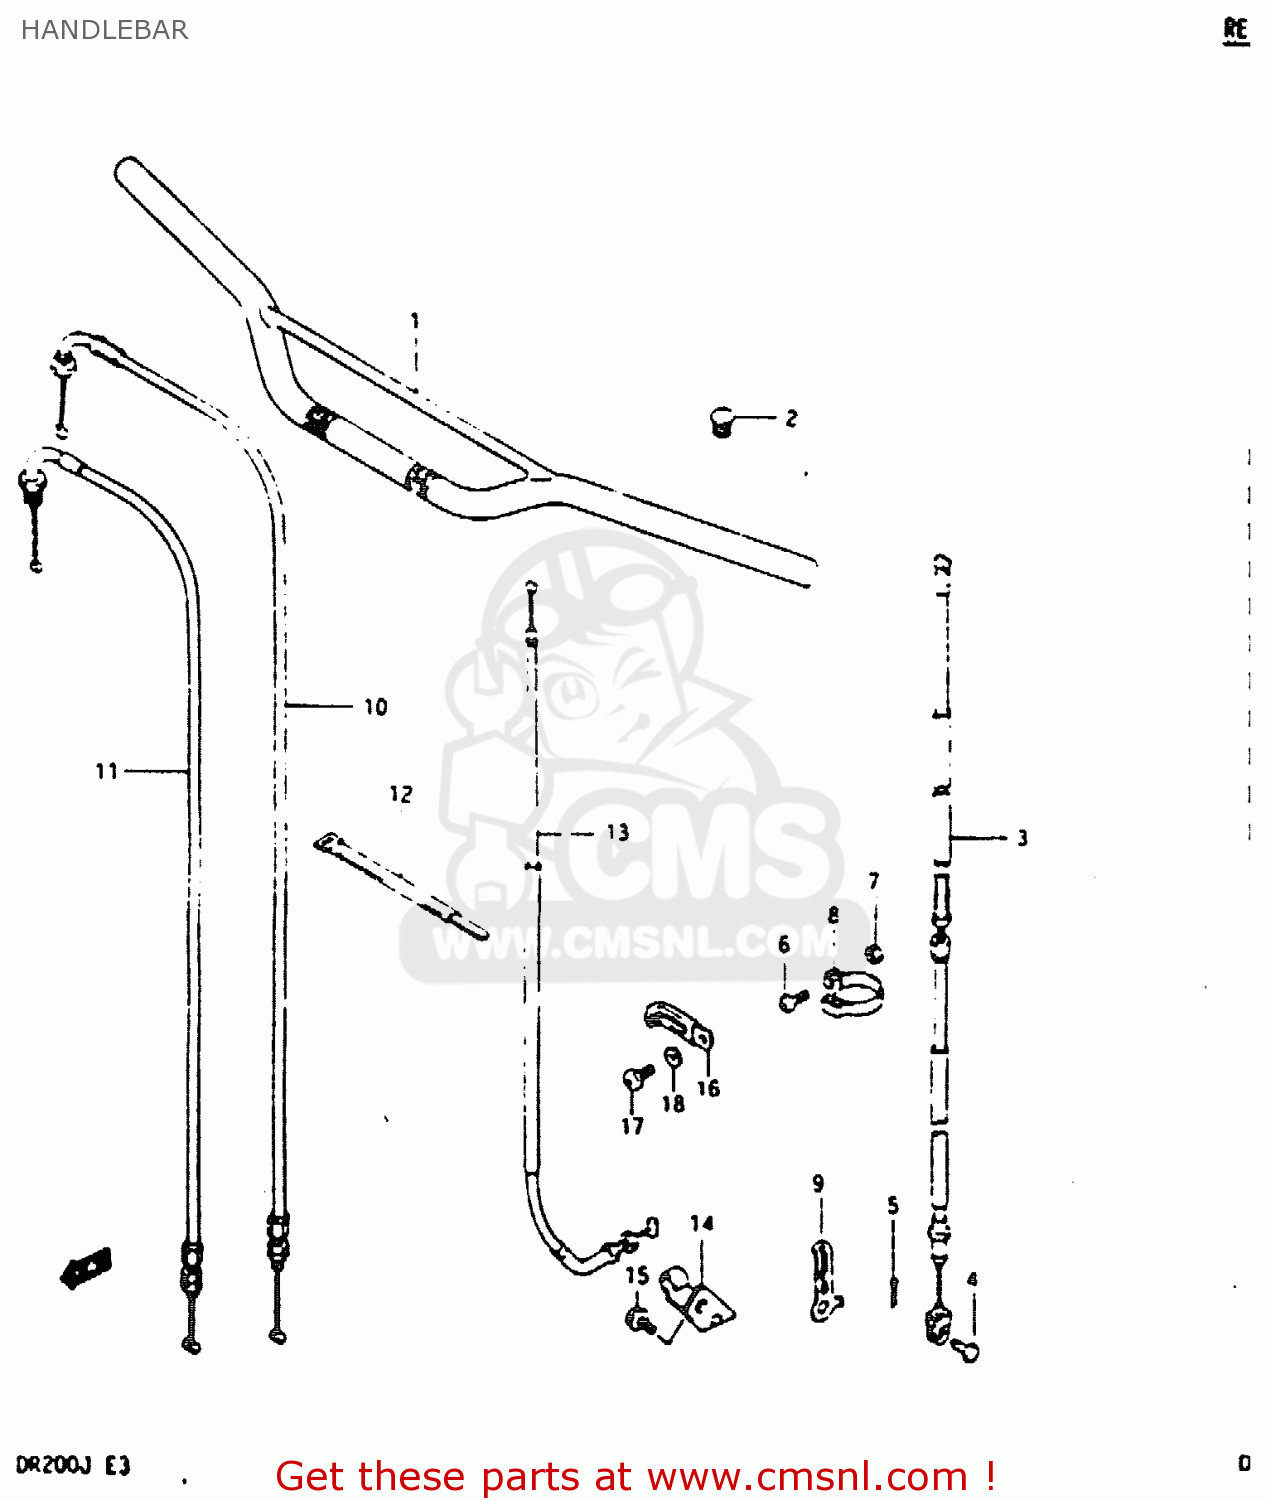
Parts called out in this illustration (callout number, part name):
1	HANDLEBAR
2	CAP(OD:14)
3	CABLE ASSY,CLUTCH
4	PIN(L:15)
5	PIN
6	SCREW
7	NUT 5MM
8	CLAMP,CABLE
9	CLAMP,CABLE
10	CABLE ASSEMBLY,THROTTLE
11	CABLE ASSEMBLY,THROTTLE
12	CLAMP
13	CABLE ASSY,DECOMP
14	BRACKET,DECOMP CABLE
15	BOLT 6X12
16	CLAMP
17	SCREW 6X12
18	WASHER,LOCK
